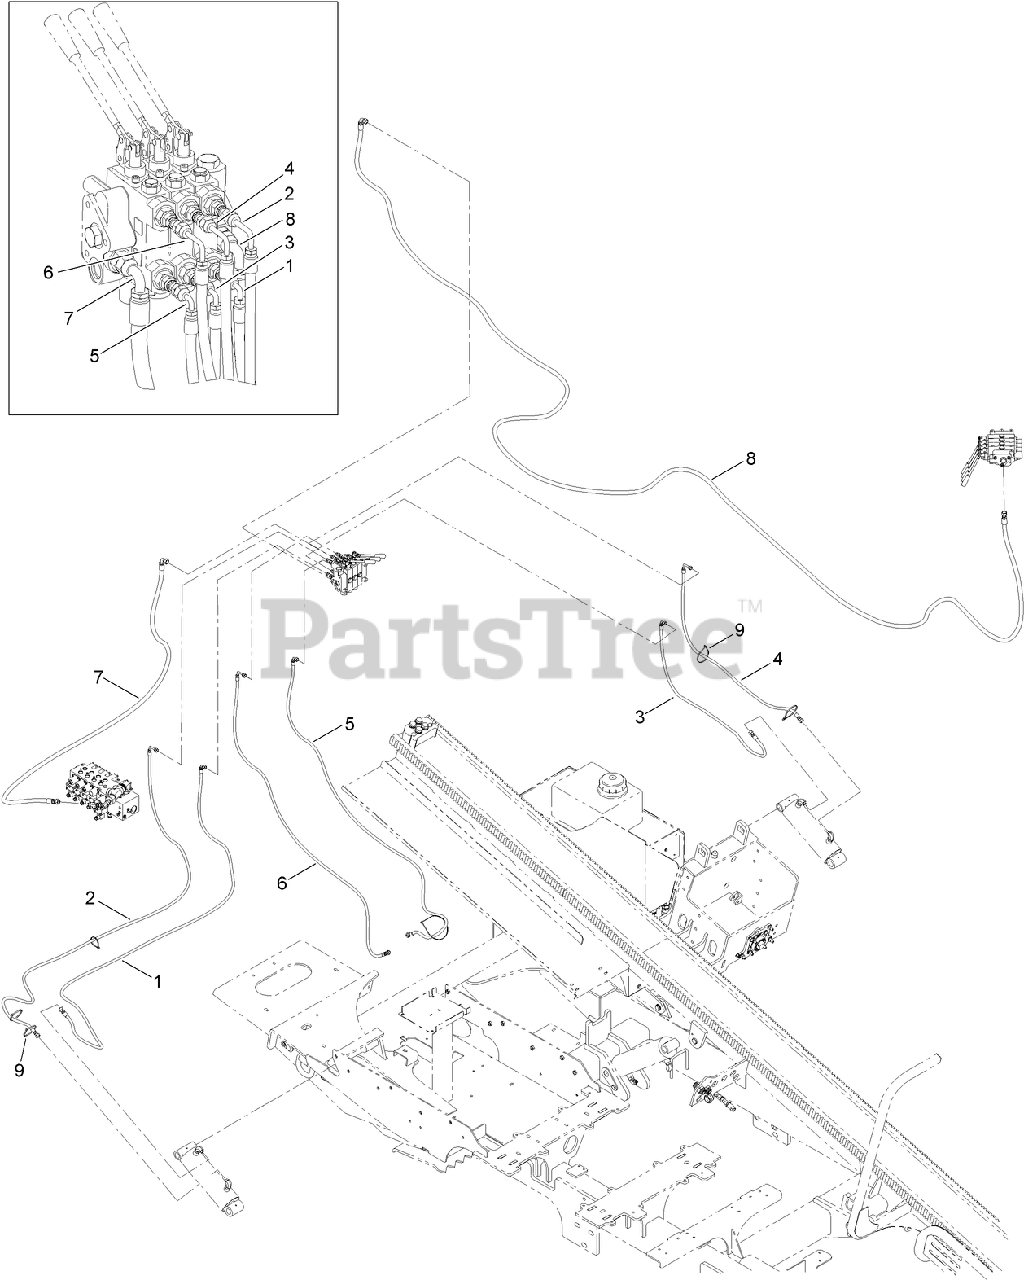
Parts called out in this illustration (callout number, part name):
1	HOSE ASM-HYD
2	HOSE ASM-HYD
3	HOSE ASM-HYD
4	HOSE ASM-HYD
5	HOSE ASM-HYD
6	HOSE ASM-HYD
7	HOSE ASM-HYD
8	HOSE ASM-HYD
9	TIE-CABLE
